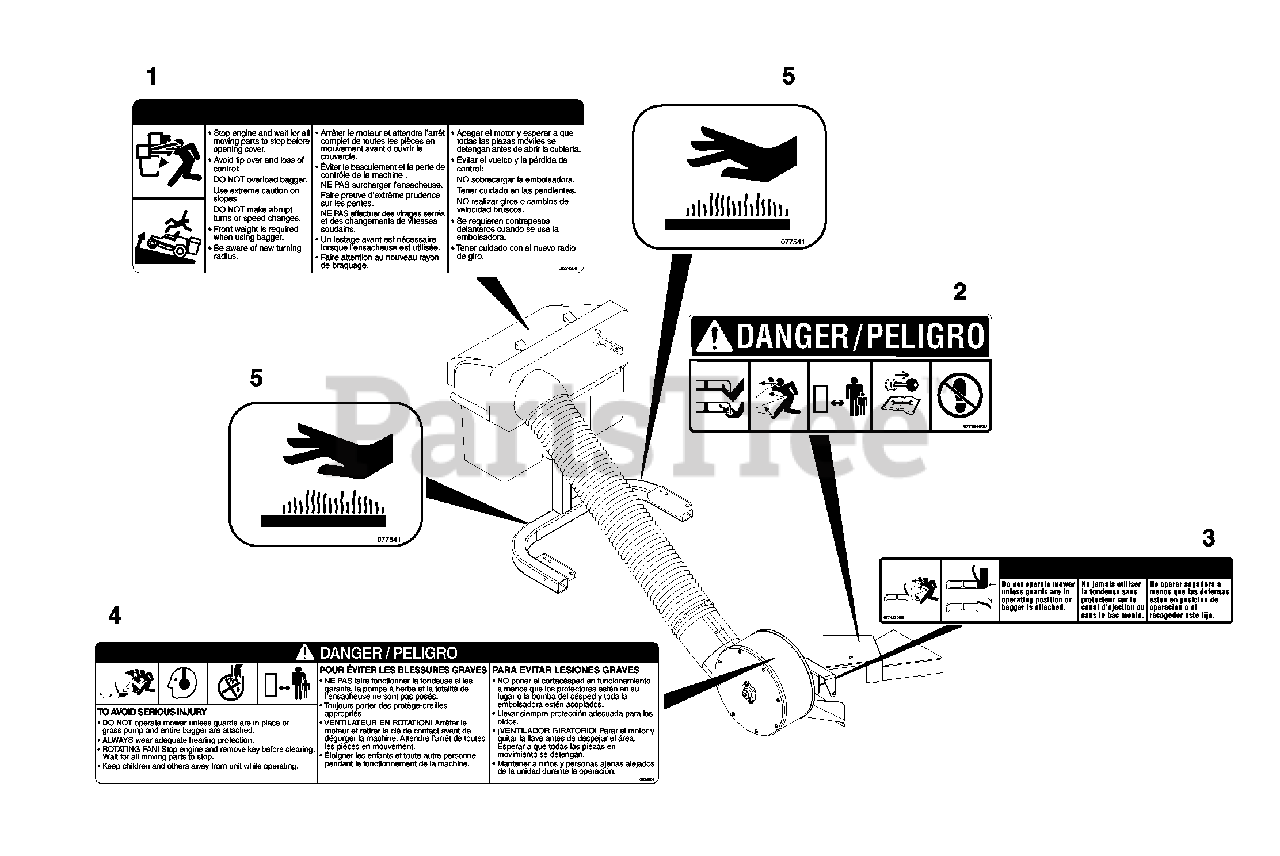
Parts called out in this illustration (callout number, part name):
1	Decal-Warning, Bagger Cover
2	Decal, Mower Pan Head Danger
3	Decal, Warning
4	Decal-Caution, Grass Pump
5	Decal, Hot Surface
